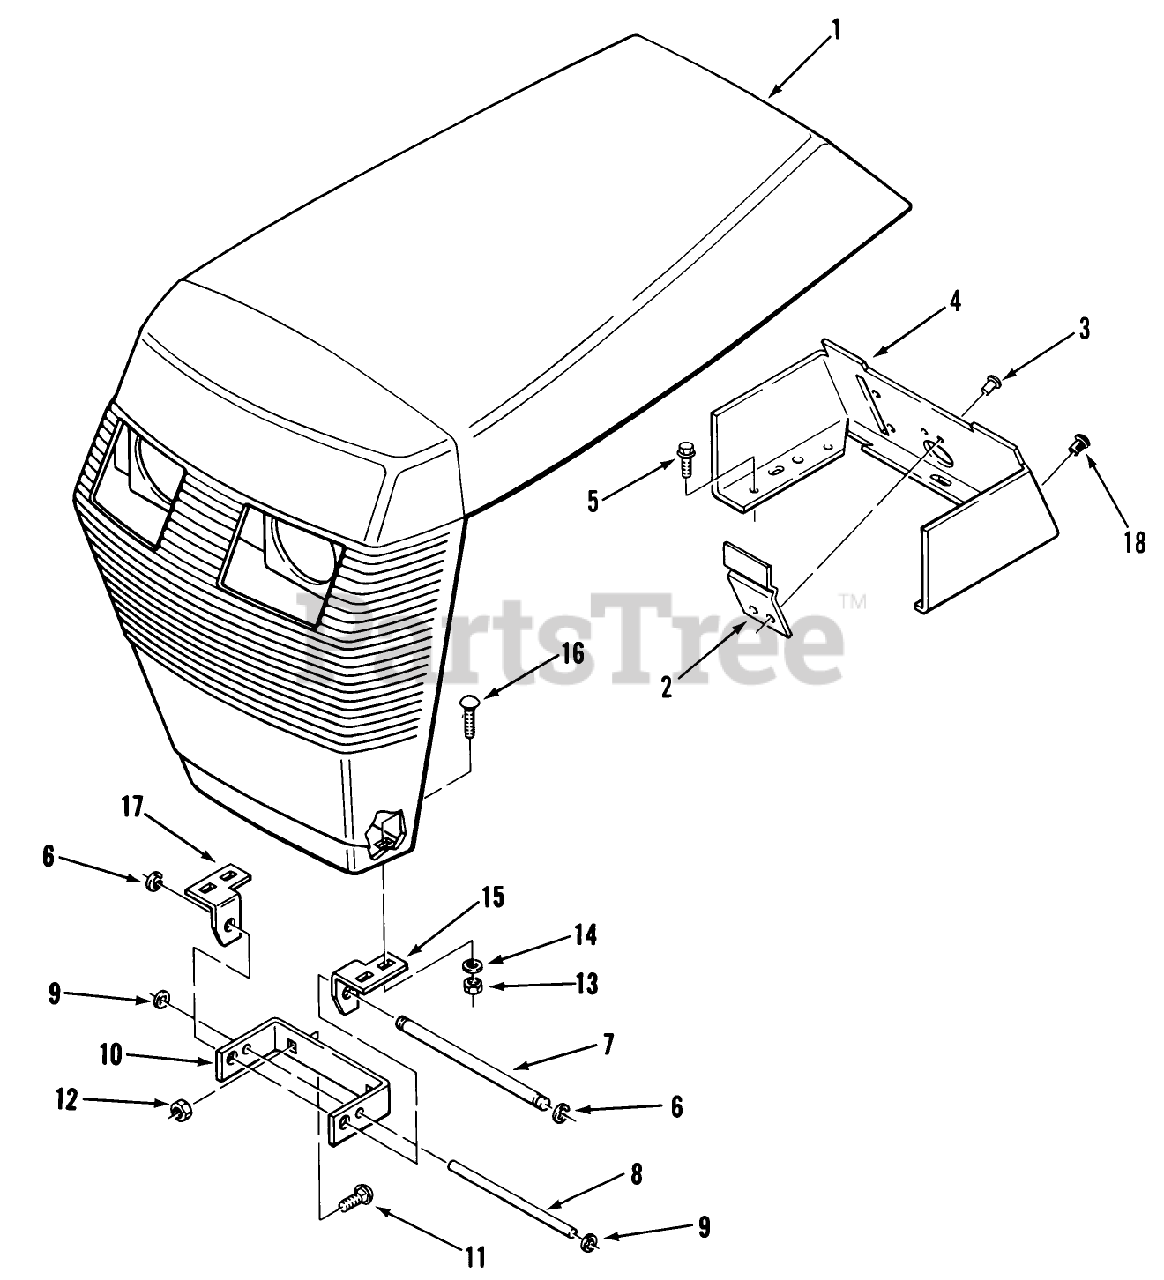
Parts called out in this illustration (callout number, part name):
2	BULLT 333A
5	SCREW
6	RING-RETAINING
7	ROD-GRILL PIVOT
8	ROD-HOOD STOP
18	NYLON PLUG
